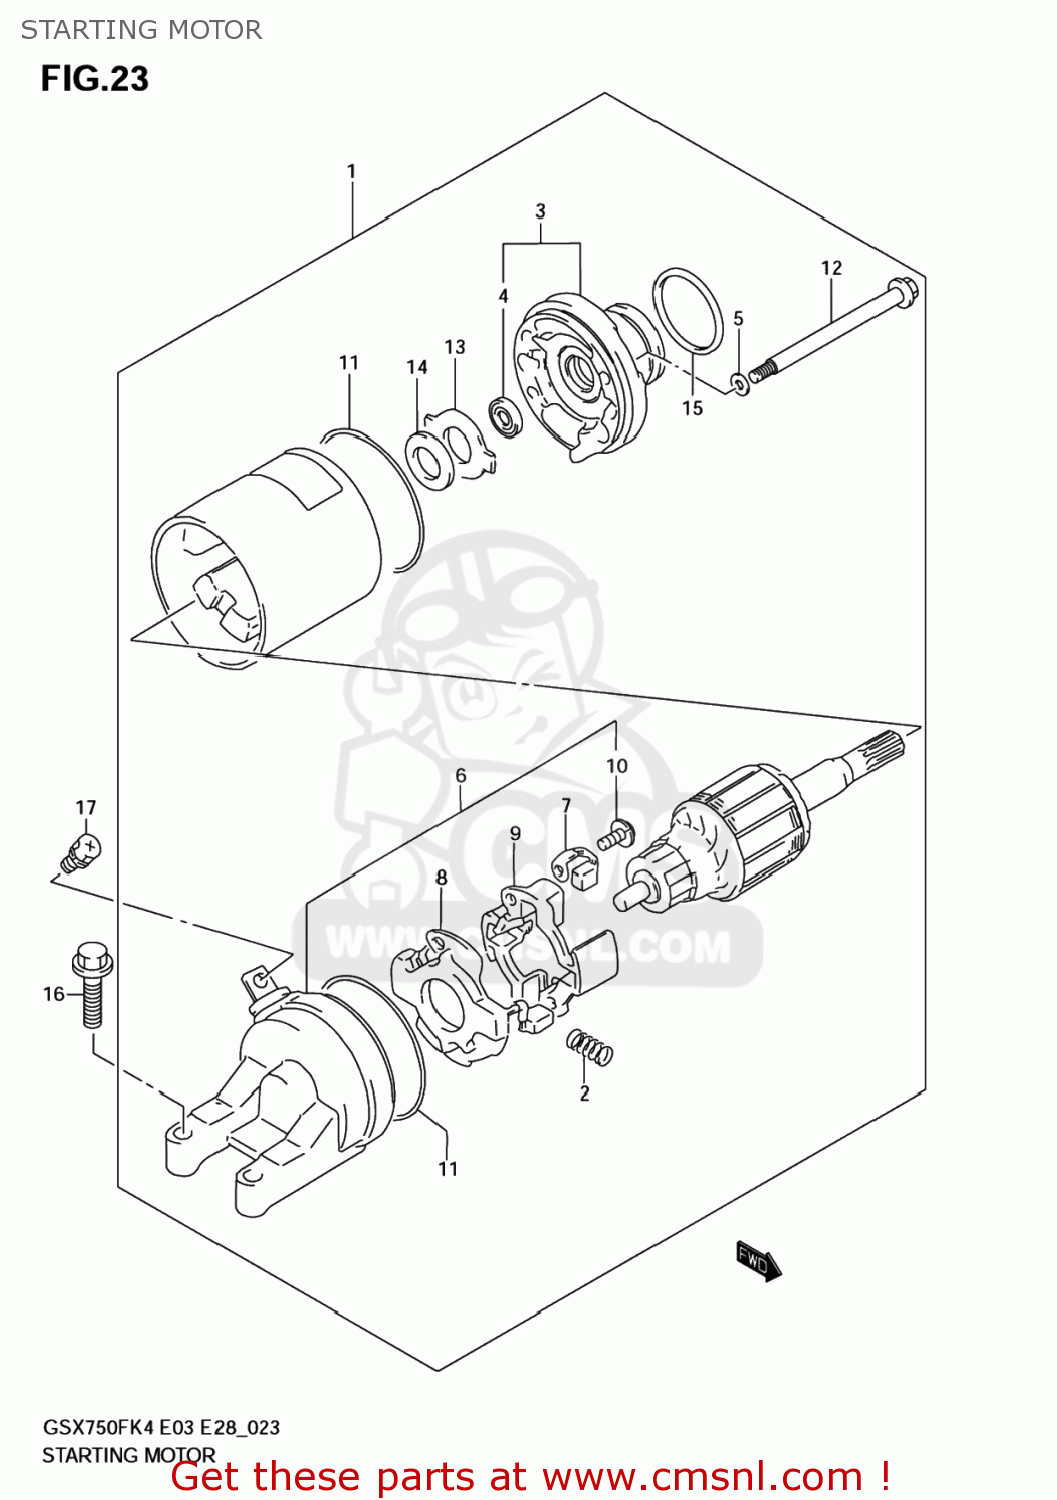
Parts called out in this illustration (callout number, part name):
1	MOTOR ASSY,STARTING
2	SPRING
3	BRACKET
4	SEAL,OIL
5	O RING
6	FRAME ASSY,COMMUTATOR
7	BRUSH
8	BRUSH SUB ASSY,STARTER
9	HOLDER,BRUSH
10	SCREW
11	O RING
12	BOLT
13	PLATE,LOCK
14	SHIM
15	O RING(D:3,ID:24.5)
16	SCREW (6X25)
17	SCREW(5X8)
